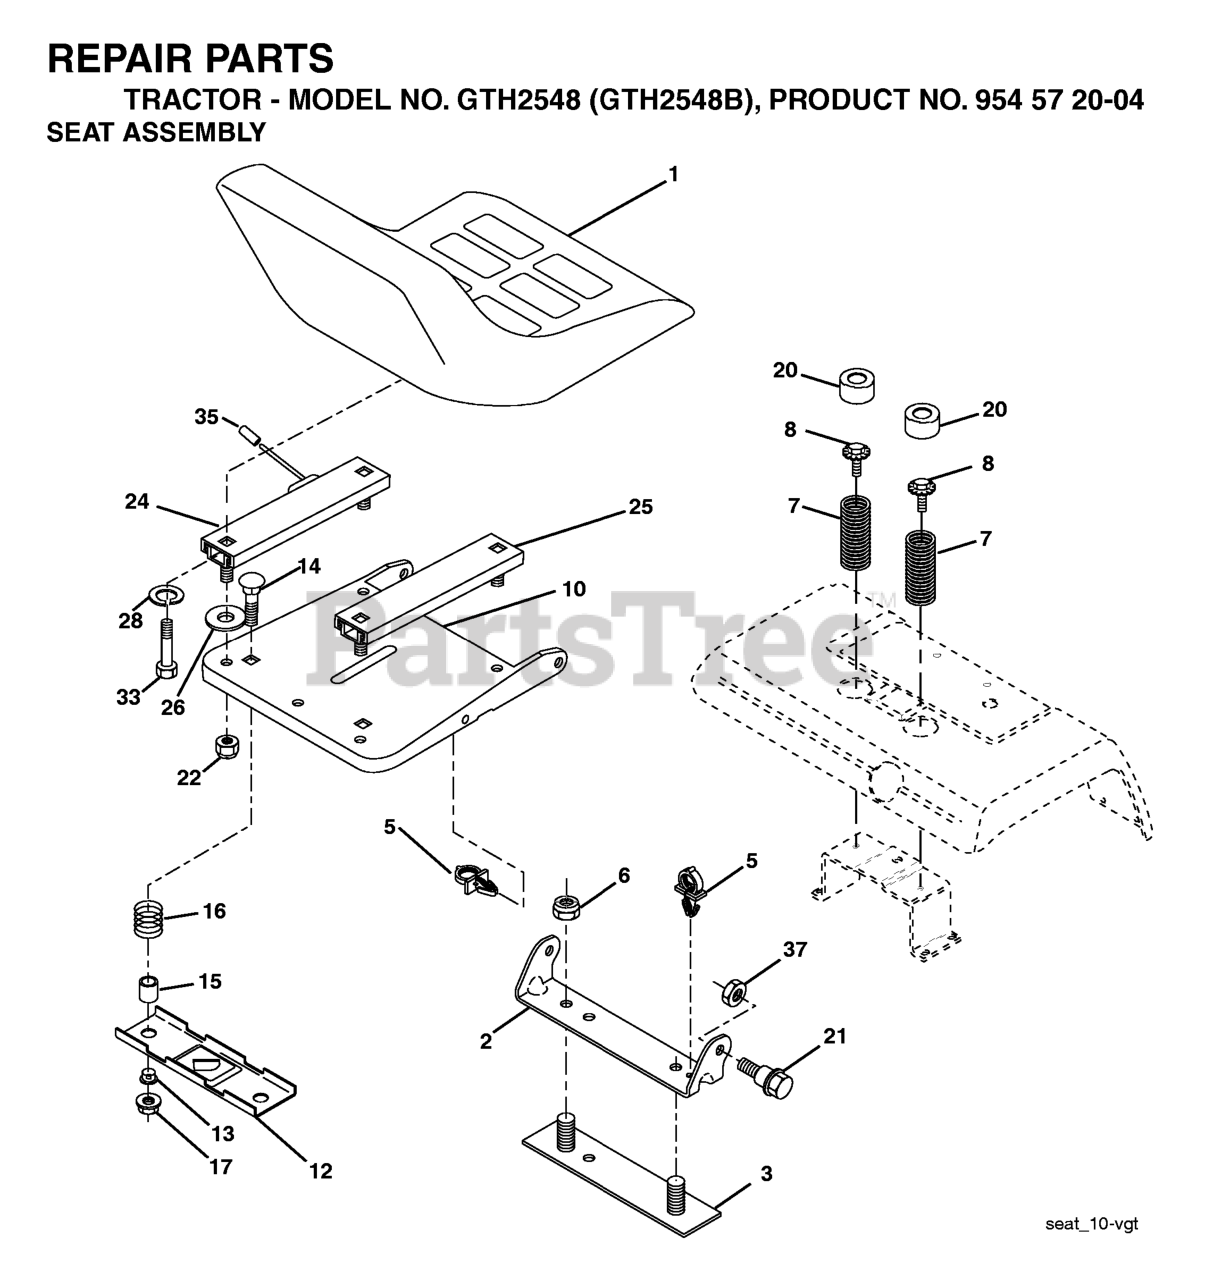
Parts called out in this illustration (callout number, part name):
1	SEAT.XH150.GRY
2	SEAT PIVOT BRKT
3	STRAP
6	NUT
7	SPRING COMPRESSION
8	BOLT.5/16-18UNCX3/4 W/SEMS.BLK
10	PAN SEAT
12	BRKT SWITCH
14	BOLT.ROUND.HEAD.SQUARE.NECK
15	SPACER SPLIT
16	SPRING COMPRESSED
17	NUT T
20	CAP SPRING
21	BOLT.SHOULDER.5/16-18
24	TRACK SLIDE, SEAT(L)
25	TRACK SLIDE, SEAT(R)
33	BOLT.FIN.HEX.5/16-18X3/4
35	CAP
37	NUT.71038.31-18.HEX.NYLOCK
